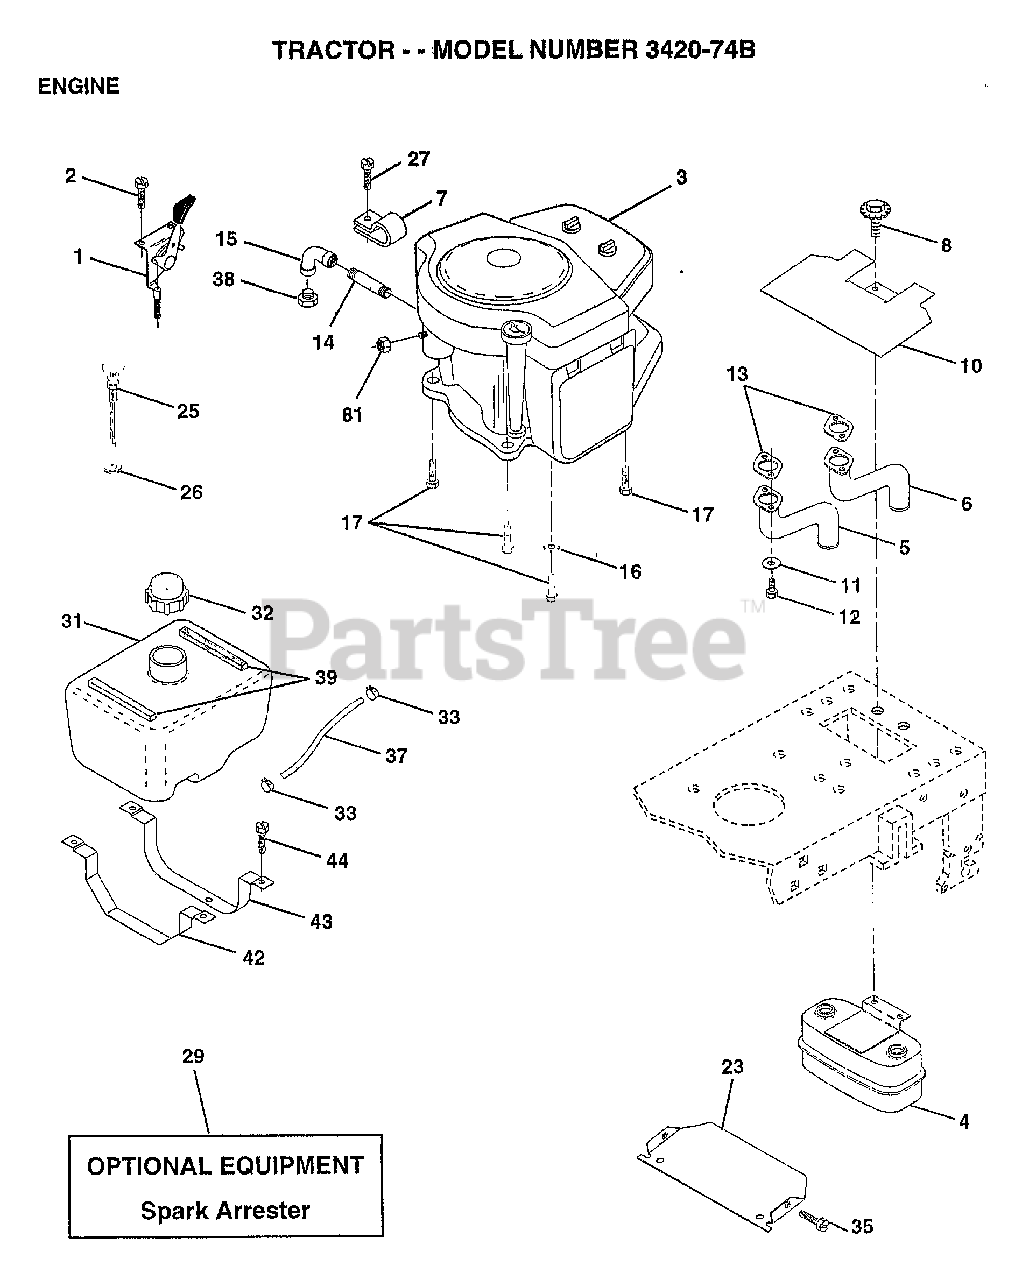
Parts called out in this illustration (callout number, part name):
2	SCREW LT
4	MUFFLER.TW.LOTONE
5	EXHAUST.B&S.18.LH
6	EXHAUST.B&S.18.RH
7	CLAMP.TUBE.DBL.EN
8	BOLT.5/16-18.UNC
10	SHIELD.HEAT.
11	LOCKWASHER
13	GASKET MUFFLER
14	PIPE NIPPLE LT
15	ELBOW
16	LOCKWASHER
17	SCREW LT
23	SHIELD-HEAT
25	"CONTROL.CHOKE.51"""
26	"NUT,KEPS 3/8-24IM"
27	"SCREW-TT,10-32 FL"
31	TANK FUEL 1.9 NAT
32	CAP ASM FUEL
33	HOSE CLAMP
35	SCREW
37	HOSE T
39	"STRIP,FORM"
42	STRAP TANK FUEL
43	STRAP TANK FRONT
44	SCREW
81	NUT
